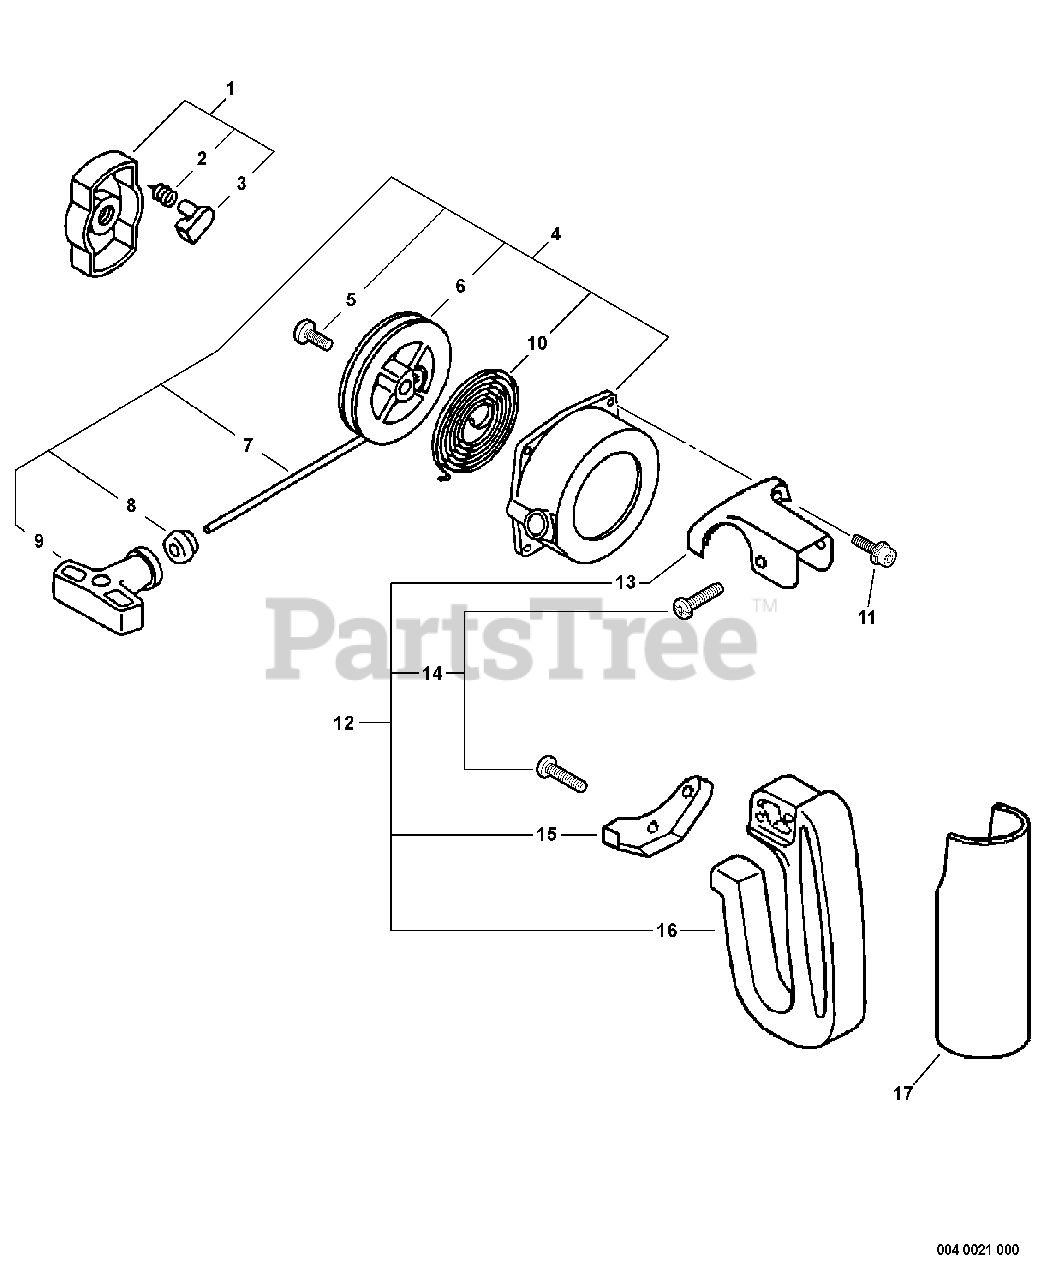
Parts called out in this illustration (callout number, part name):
1	PAWL ASSY, STARTER
2	SPRING, RETURN
3	PAWL, STARTER - BLACK
4	STARTER ASSY
5	SCREW
6	REEL, ROPE
7	ROPE, STARTER
8	GUIDE, ROPE
9	GRIP, STARTER
10	SPRING, RECOIL
11	BOLT 4×18
12	SIDE HANDLE ASSY
13	BRACKET, HANDLE
14	SCREW 5×16
15	BRACKET, HANDLE
17	GRIP, HANDLE
